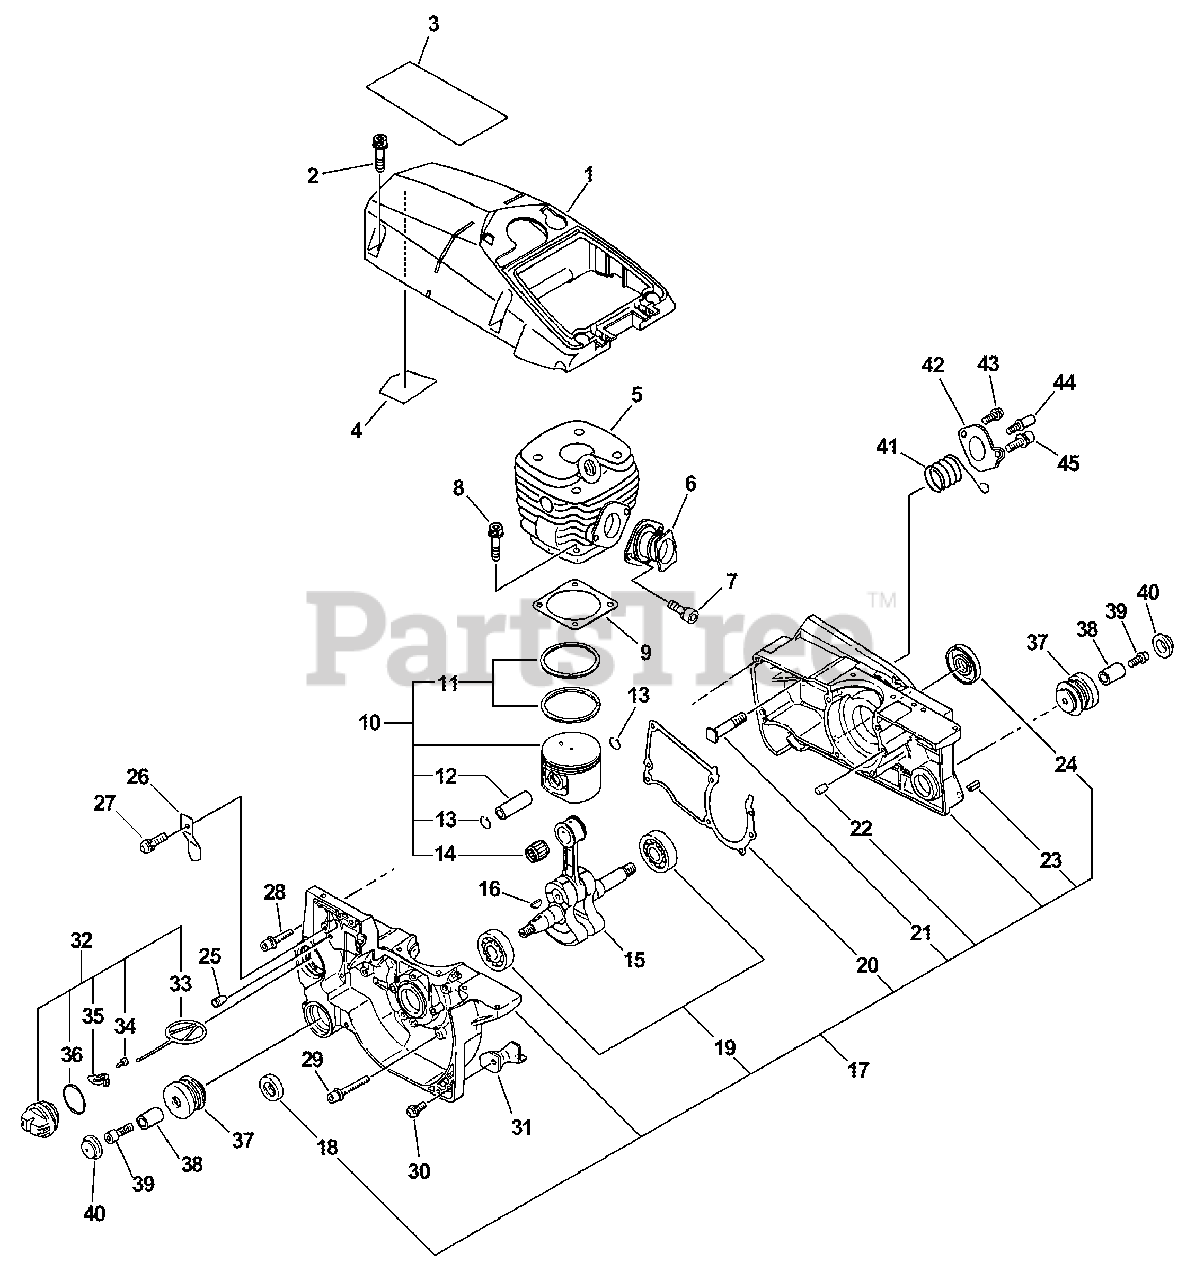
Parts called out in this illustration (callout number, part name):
1	COVER, ENGINE
2	SCREW - 5X20
3	LABEL - CAUTION
4	DEFLECTOR, HEAT
5	CYLINDER
6	BELLOWS, INTAKE
7	SCREW - 5X14
8	SCREW - 5X25
9	GASKET, CYLINDER
10	PISTON KIT
11	RING, PISTON
12	PIN, PISTON
13	RING, RETAINING
14	BEARING, NEEDLE
15	CRANKSHAFT ASSY
17	CRANKCASE KIT
18	SEAL, OIL
19	BEARING, BALL - 6202
20	GASKET, CRANKCASE
21	STUD, GUIDE BAR
22	PIN - LOCATING
23	PIN - SPRING -- 5X10
24	SEAL, OIL
25	VENT, TANK
27	SCREW - 4X8
28	SCREW - 5X20
29	SCREW - 5X35
30	SCREW - 5X14
32	CAP ASSY - ORANGE
33	CONNECTOR, CAP
34	SCREW - 3X8
35	RETAINER
36	O-RING - 25
37	CUSHION
38	COLLAR - 5
39	SCREW - 5X25
40	CAP, CUSHION
43	SCREW - 4X8
44	STUD, THREADED
45	SCREW - 5X14
